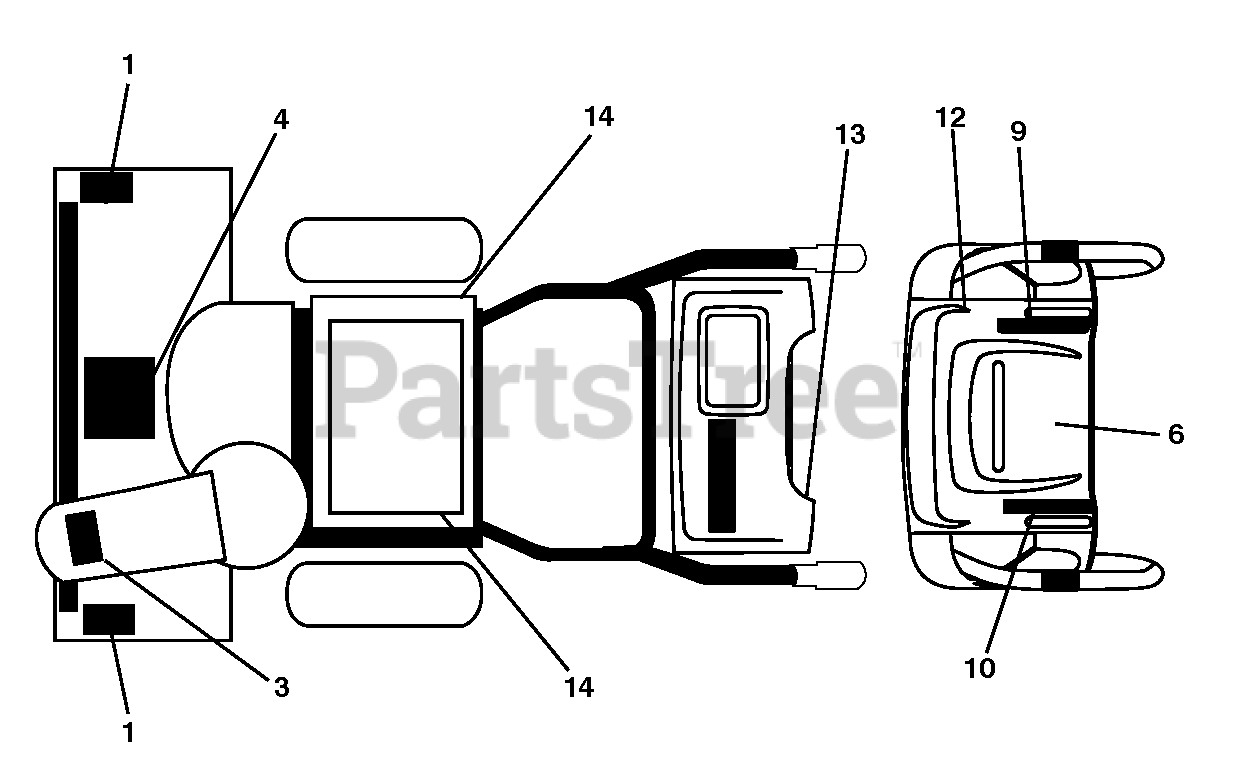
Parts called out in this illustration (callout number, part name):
1	DECAL.AUGER.SAFETY.
3	DECAL.CHUTE.SAFETY.
4	DECAL.AUGER."
6	DECAL.CONSOLE.INSTRUCTION
10	Decal, Console LT SPD/LEV/P WRST
13	DECAL.FENDER
14	DECAL.BELT.GUARD.
